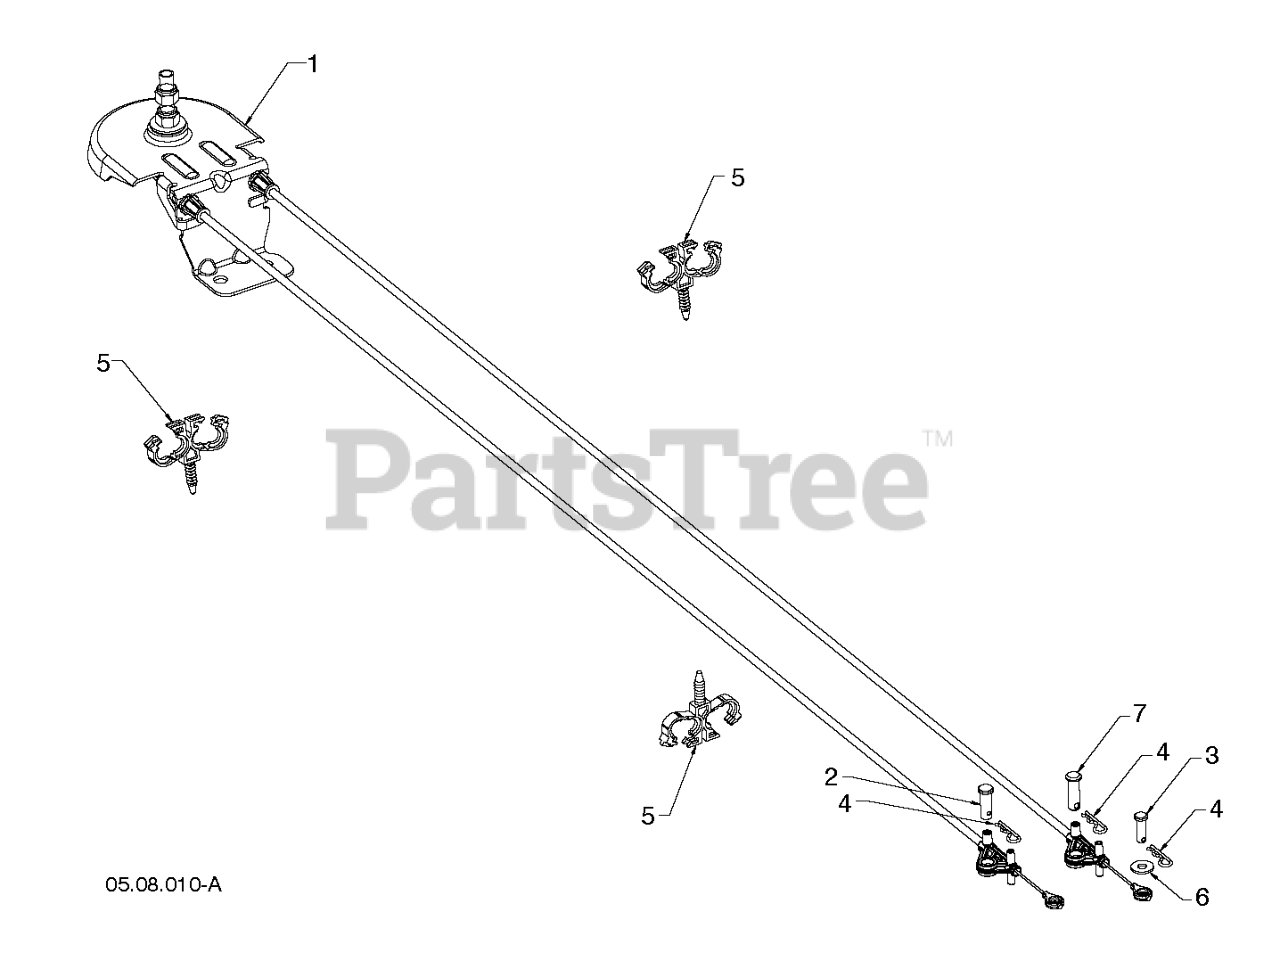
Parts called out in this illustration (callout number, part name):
1	CABLE.CHUTE.ROTATOR.ASM
2	PIN CLEVIS 5/16X.875
3	PIN.CLEVIS
4	HAIRPIN.SOFT.ZINC.059X1.125
5	CLIP.CONDUIT.DOUBLE LOOP
6	WASHER FLAT_.250 X .625 X .06
7	PIN CLEVIS 5/16 X 1.0 L
